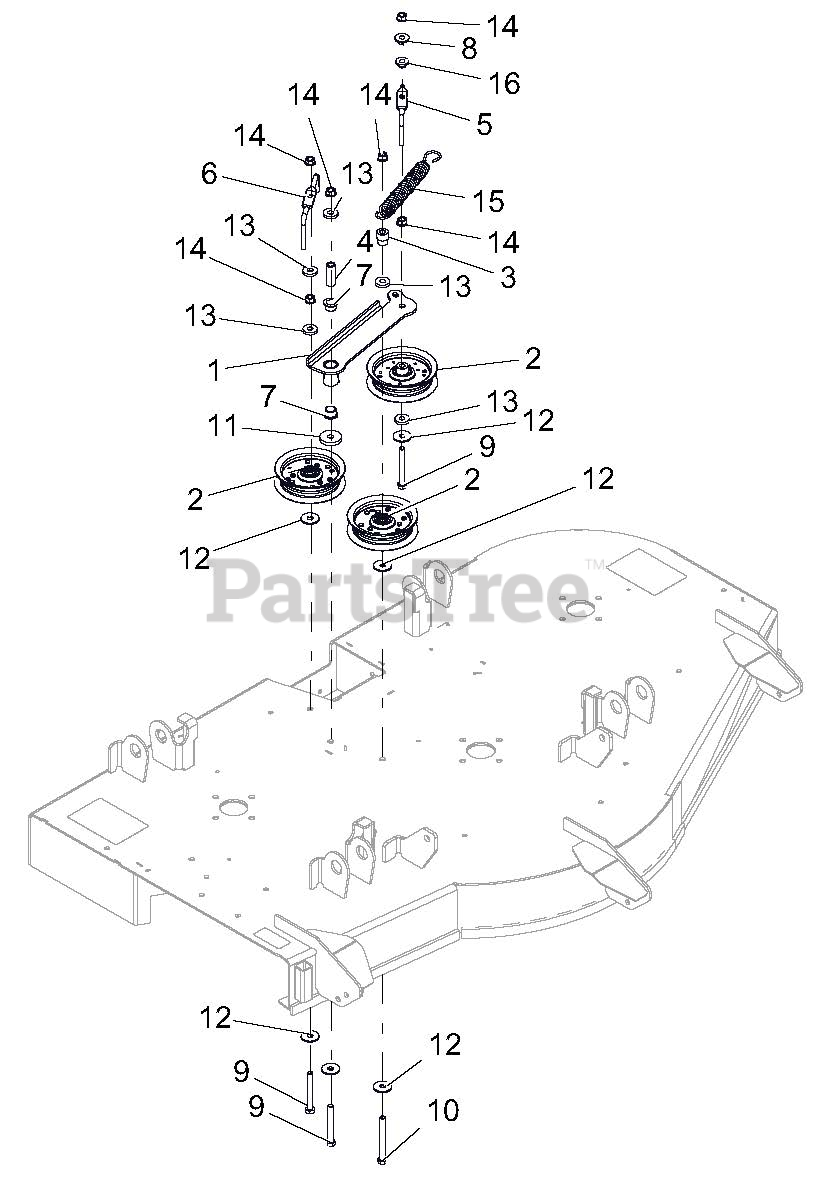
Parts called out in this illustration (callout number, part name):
1	WLDMT, IDLER ARM-52"
2	ASM, IDLER 4"
3	BUSHING, IDLER (P/M)
4	SPACER, .375IDX.625ODX1.66 PM
5	WIREFORM, BELT FINGER
6	WIREFORM, BELT FINGER
7	BSHG-FLG, .625X.750X.500X1.00
8	BSHG-FLG .385X.500X.875X.31
9	BLT-HEX .38-16X3.00 GR5 FTH YZ
10	@BLT-HEX .38-16X3.50 GR5 YWZC
11	WSHR,FLT STL.406X1.50X.245YWZC
12	@WSHR-FL-STL .406X1.25X.10 ZC
13	WSHR-FL-STL .406X1.00X.188 YWZ
14	@NUT-LK-TOP-FLG .38-16 YWZC
15	SG-TENS .135X.98X6.0 WLD 62
16	BSHG-FLG .385X.500X.875X.406
